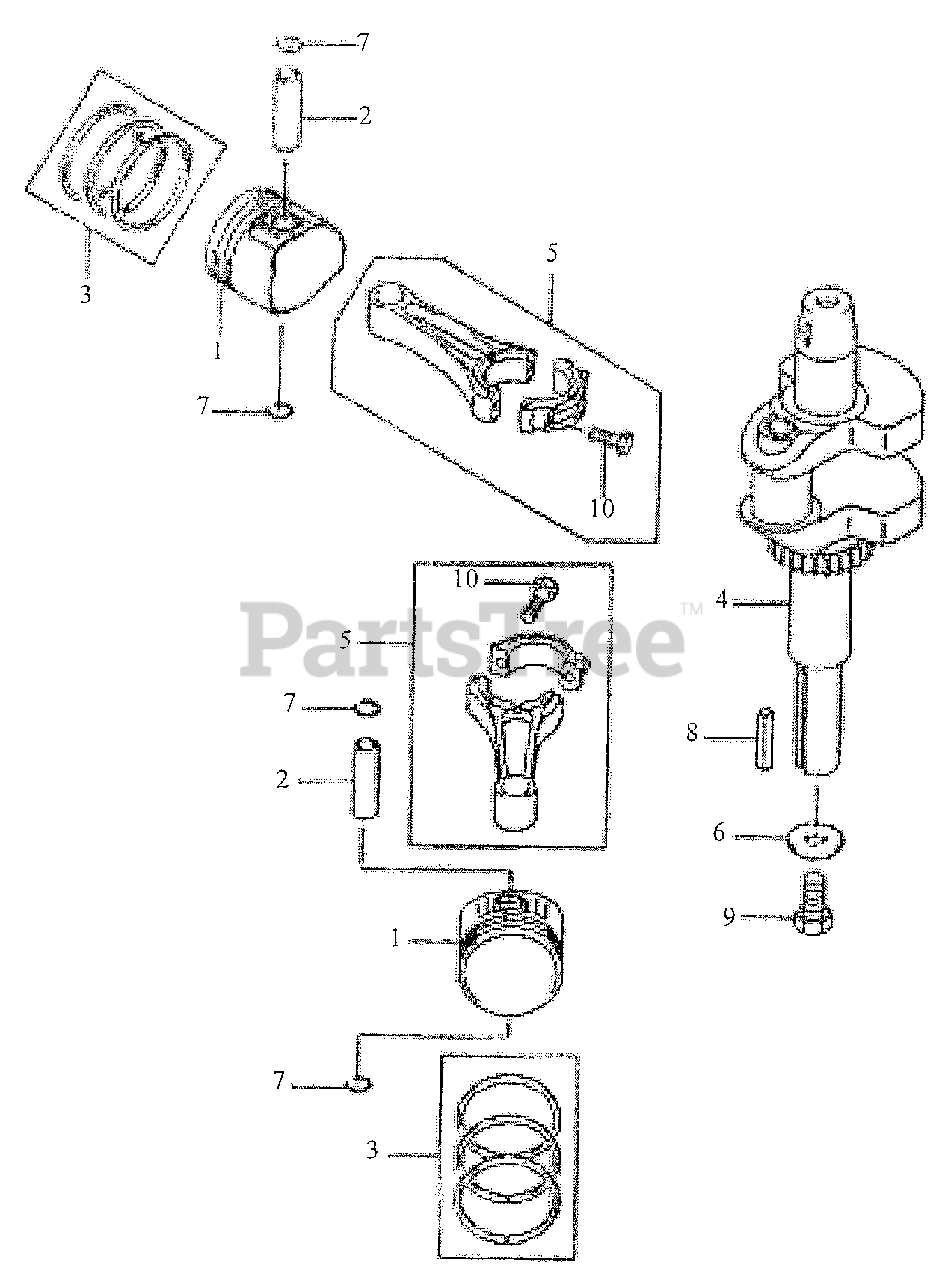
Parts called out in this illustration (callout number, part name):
1	Piston, Engine
3	Ring-Set, Piston
5	Rod-Connecting
10	Bolt, Flange
